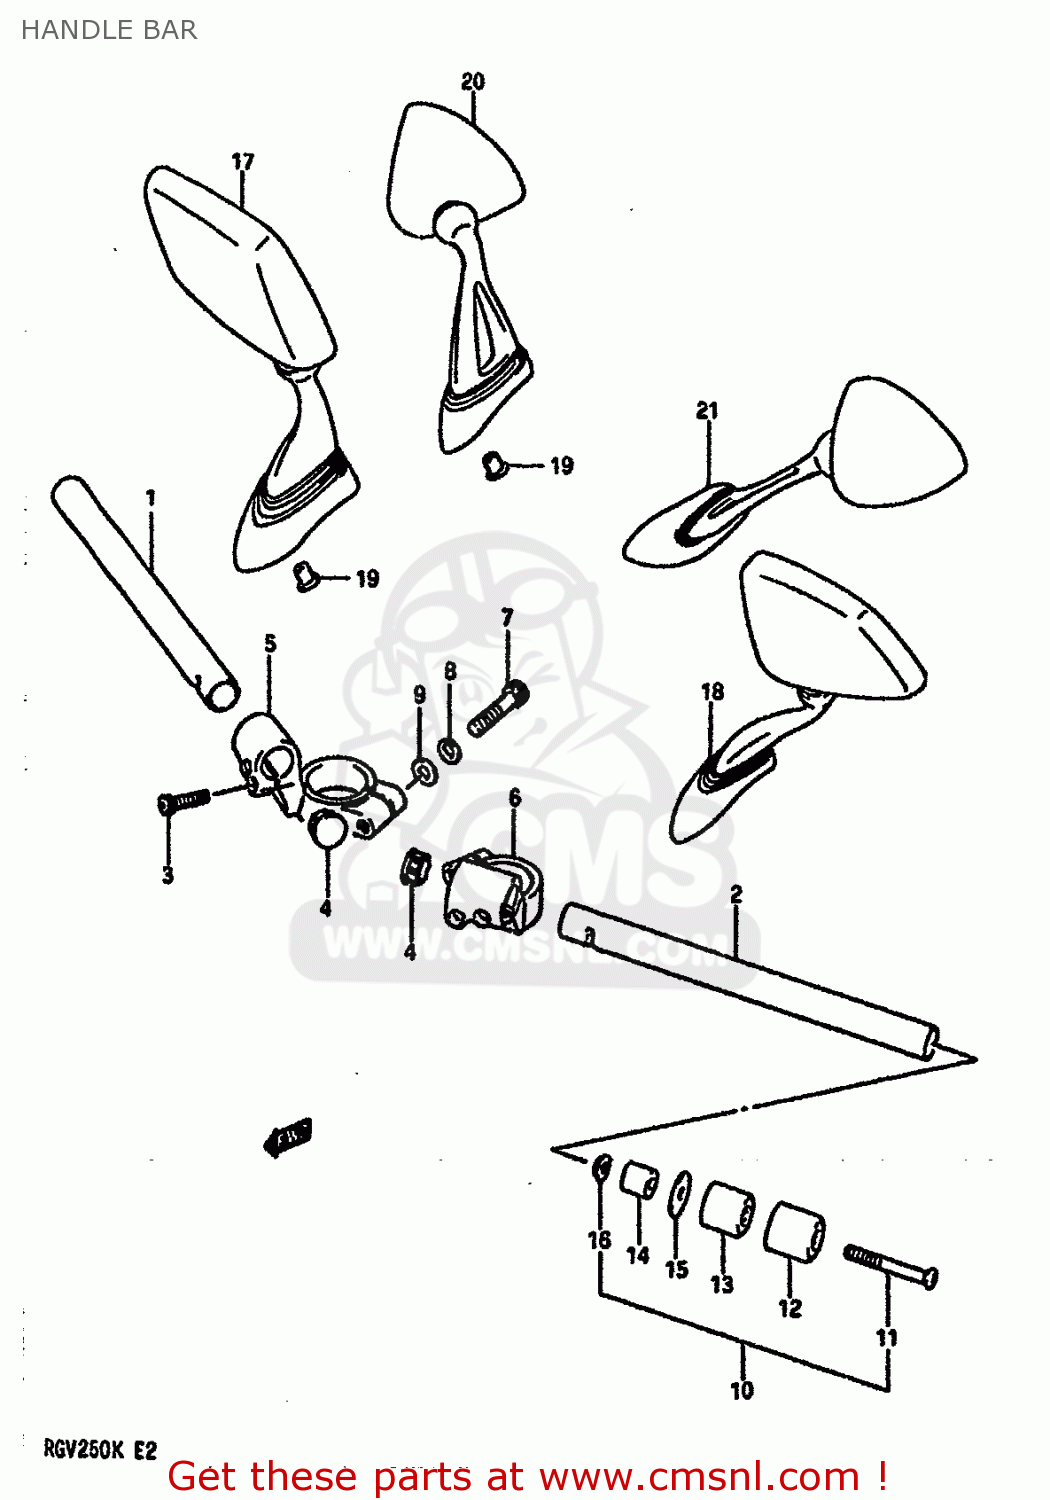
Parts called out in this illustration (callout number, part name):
1	HANDLEBAR,R
2	HANDLEBAR,L
3	BOLT
4	CAP,HANDLEBAR
5	HOLDER,HANDLE BAR RH
6	HOLDER,HANDLE BAR LH
7	BOLT, RH
8	LOCK WASHER
9	WASHER
10	BALANCER SET,HANDLE BAR
11	SCREW
12	CAP,BALANCER
13	BALANCER,HANDLE
14	EXPANDER,BALANCER
15	SPACER,BALANCER
16	NUT
17	MIRROR ASSY,REAR VIEW RH
18	MIRROR ASSY,RR VIEW,L
19	NUT,RR VIEW MIRROR
20	MIRROR ASSY,RR VIEW,R
21	MIRROR ASSY,REAR VIEW LH
